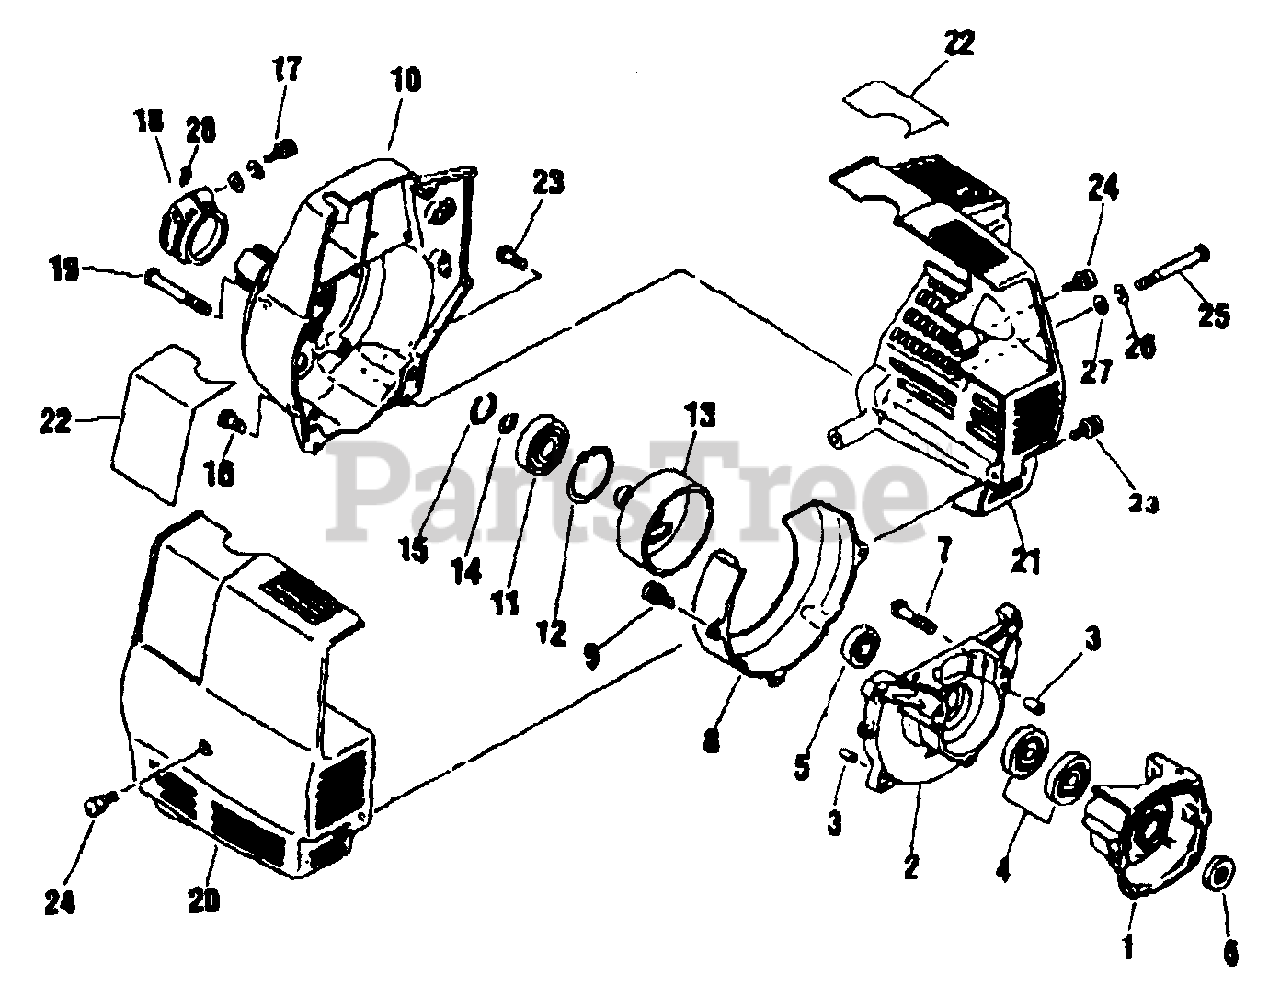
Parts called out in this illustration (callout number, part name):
1	CRANKCASE - REAR
2	CRANKCASE - FRONT
3	PIN, DOWEL
4	BEARING, BALL 6001
5	SEAL, OIL 12
6	SEAL, OIL
7	BOLT 5×25
8	DEFLECTOR, AIR
9	SCREW
10	CASE, FAN
11	BEARING, BALL 6201
12	RING, SNAP Ø32
13	DRUM, CLUTCH
14	RING, SNAP Ø12
15	RING, RETAINING
17	SCREW
18	CLAMP
20	ENGINE COVER (L)
21	ENGINE COVER (R)
22	NAME PLATE
24	SCREW
26	WASHER, SPRING 5
27	WASHER, FLAT 5.5×10×0.8
28	SHIM
